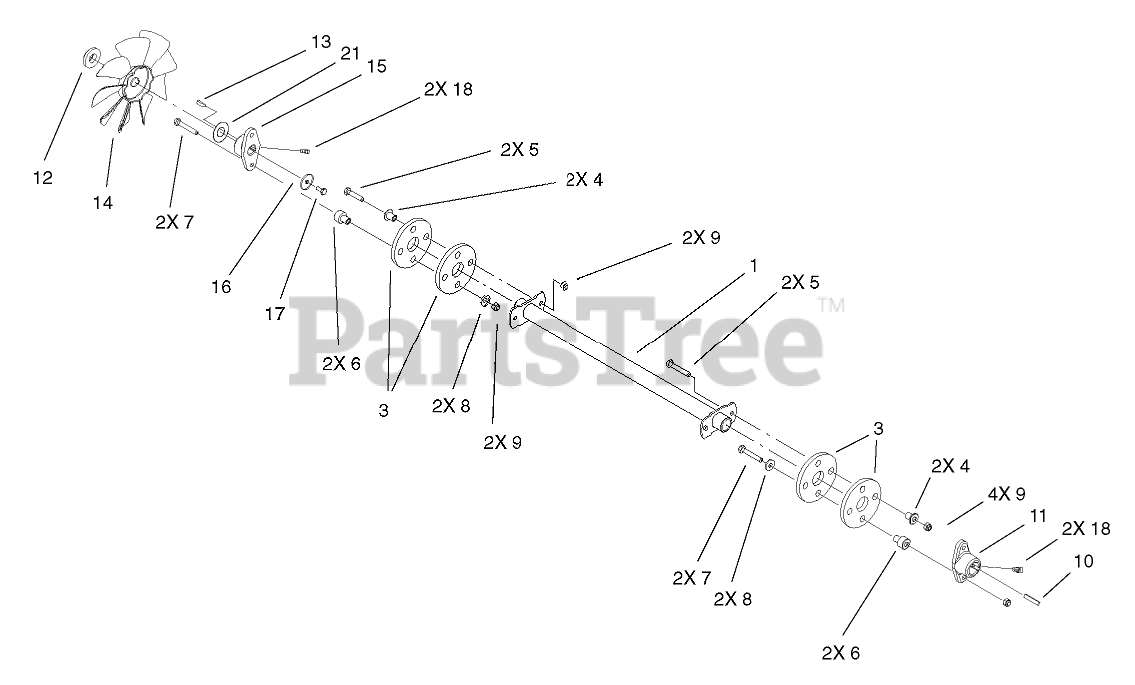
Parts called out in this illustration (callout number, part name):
1	SHAFT-DRIVE
3	COUPLING-RUBBER
4	SPACER
5	SCREW-HH
6	SPACER
7	SCREW-HH
8	WASHER-FLAT
9	NUT-LOCK, NI
10	KEY-SQUARE
12	SPACER-FAN
13	KEY-WOODRUFF
14	FAN-HYDRO
16	WASHER
17	SCREW-HH
18	SCREW-SET
21	WASHER - FAN
